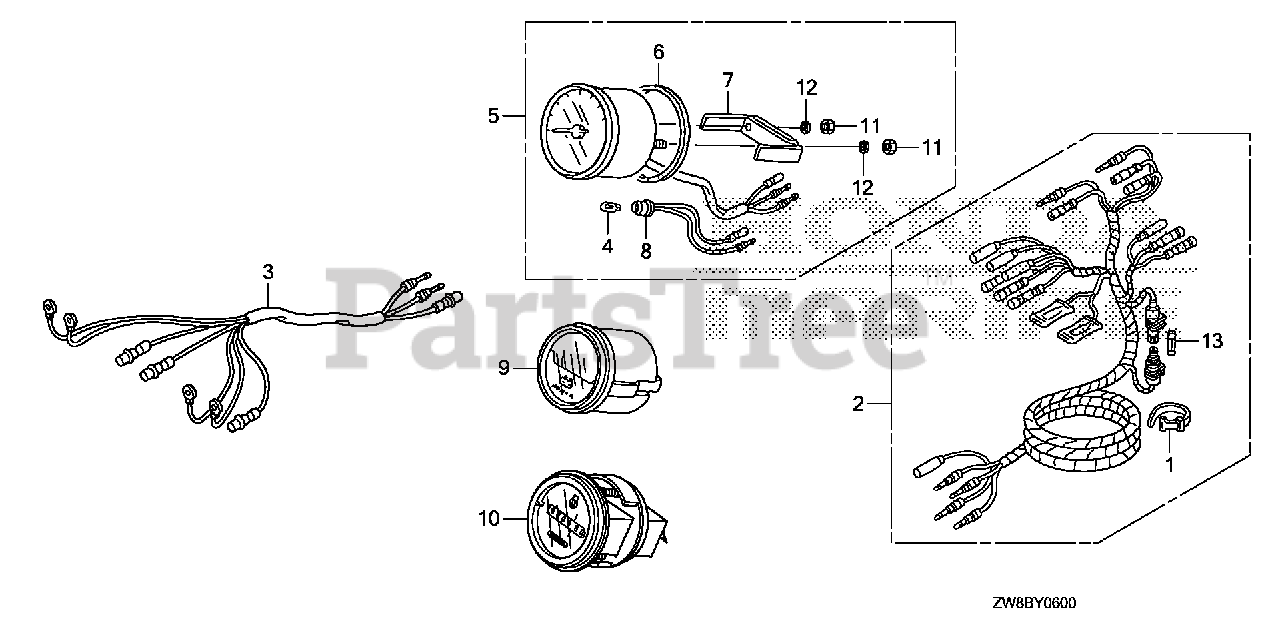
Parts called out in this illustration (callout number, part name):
1	BAND B1, CABLE Use up to Frame SN 1001879.
2	HARNESS ASSY., METER (A)
3	HARNESS ASSY., METER (B)
4	BULB, WEDGE BASE (T10) (12V 1.7W) (STANLEY)
5	TACHOMETER ASSY.
6	GASKET
7	BRACKET (TO 1015209) (FROM 1015210)
8	SOCKET (TO 1015209) (FROM 1015210)
9	METER ASSY., VOLT
10	METER ASSY., HOUR L.C.D.
11	NUT, HEX. (5MM)
12	WASHER, SPRING (5MM)
13	FUSE A (10A)
